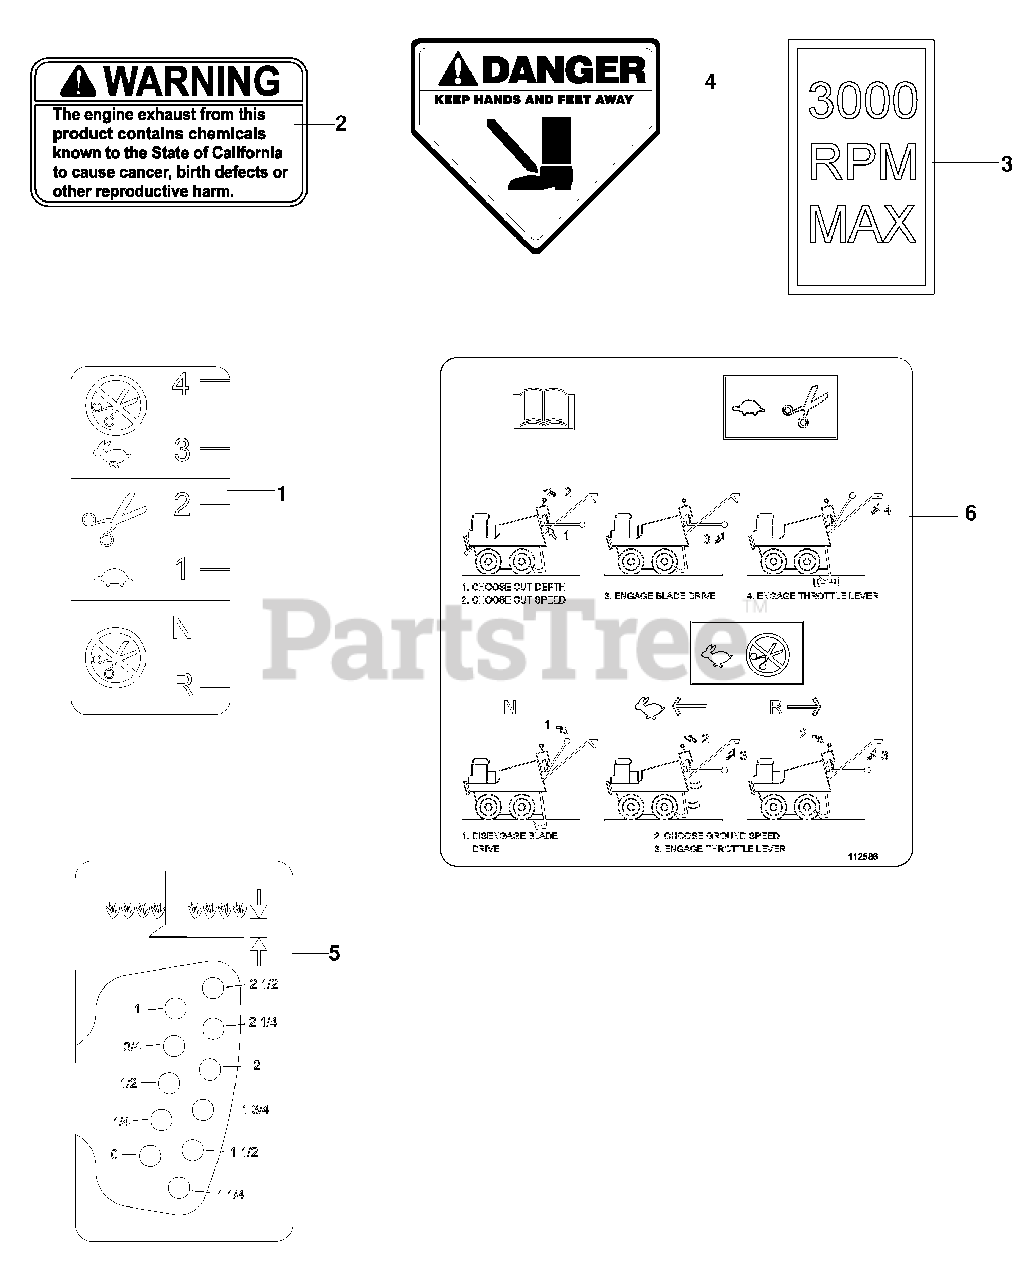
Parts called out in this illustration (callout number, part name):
1	DECAL, SHIFT
2	DECAL, PROP 65
3	DECAL, 3000 MAX RPM
4	DECAL, DANGER FOOT
5	DECAL, DEPTH OF CUT
6	DECAL, OPERATION
